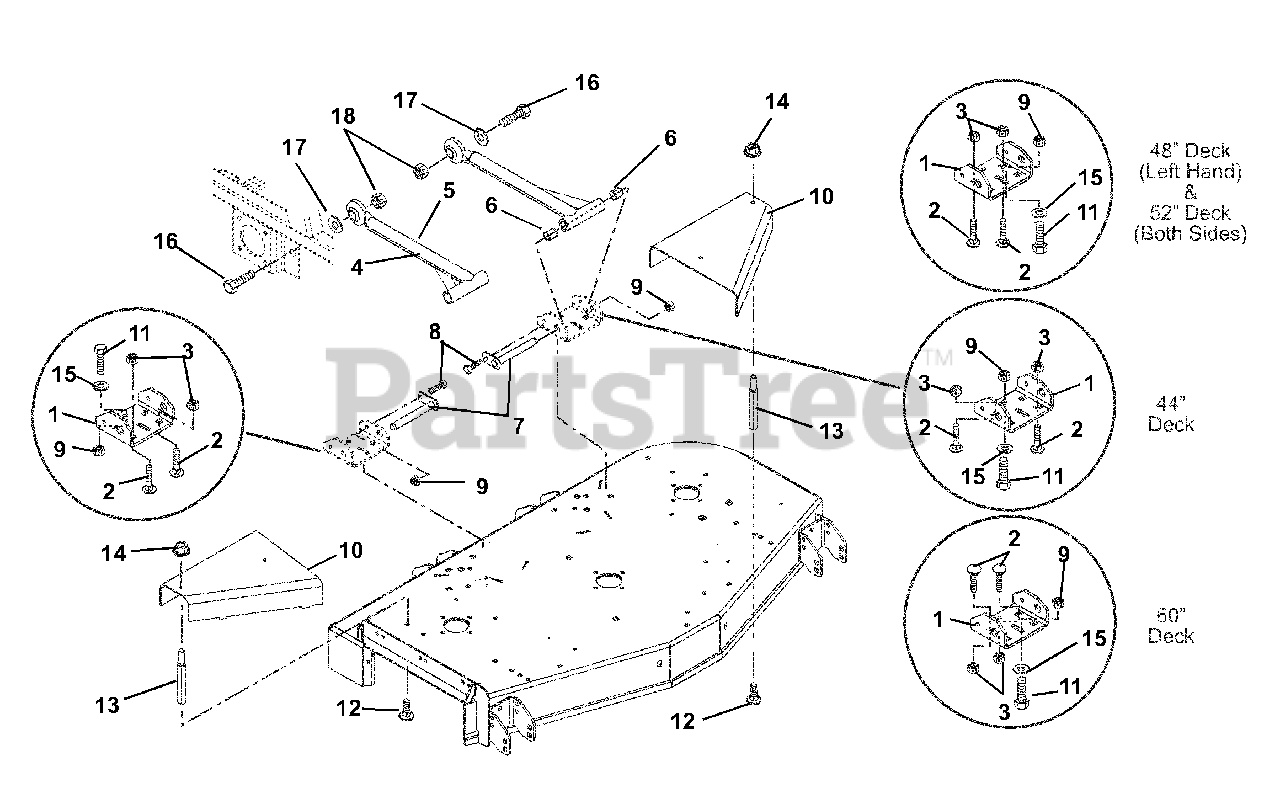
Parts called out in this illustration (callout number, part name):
1	Bracket, Mower Mounting (Rear)
2	Bolt, Round Head Square Neck .50-13 x .75 Grade 5
3	Nut, Locking Center Jam .50-13
4	Assembly, Mower Mounting
5	Mower Mounting Arm
6	Bearing, .75 x .875 x 1.00
7	Weldment, Mower Mounting Pin
8	Bolt, Hex .38-16 x .75 Grade 5
9	Nut, Locking Top Flange .38-16
10	Guard, Pulley Left Hand (079, 081)
10	Guard, Pulley Right Hand (079, 081)
10	Guard, Pulley Left Hand (080, 082)
10	Guard, Pulley Right Hand (080, 082)
10	Guard, Pulley (064, 077, 083, 310)
11	Bolt, Round Head Square Neck .38-16 x .75 Grade 5
12	Bolt, Round Head Square Neck .31-18 x .75
13	Standoff, 2.75 x .312-18
14	Nut-Locking-Top-Flange .31-18
15	Washer, Flat Steel .406 x .812 x .065
16	Bolt, Hex .875-9 x 2.75 Grade 5
17	Washer, Flat Steel .875 x 1.50 x .120
18	Nut, Locking Center .875-9
